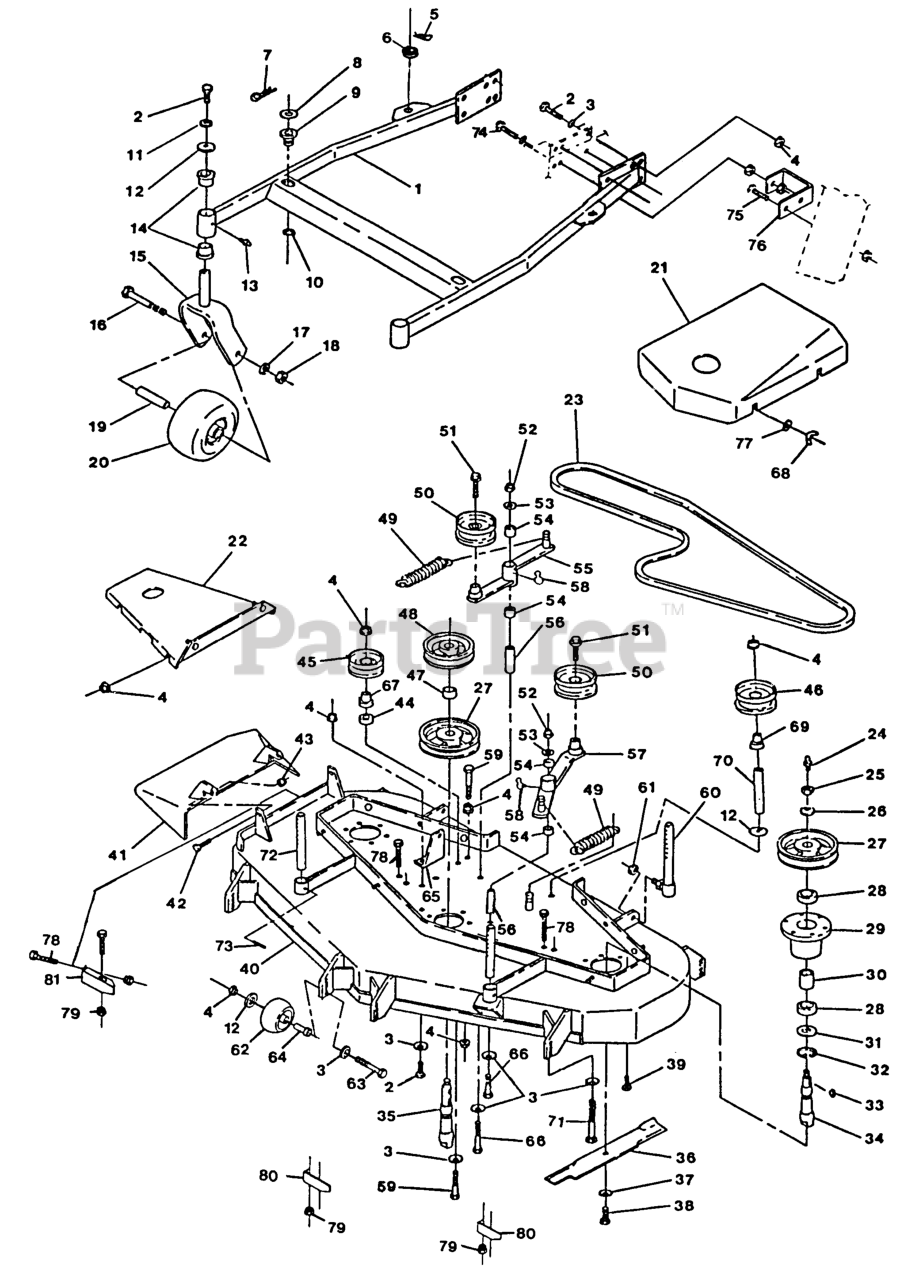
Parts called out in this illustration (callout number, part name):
5	PIN,HAIR COTTER
8	WASHER-FLAT
9	BUSHING-DECK
14	BEARING-FLANGED
23	BELT,BLADE DRIVE
26	WASHER-SPRING
27	SHEAVE,BLADE DRIVE
30	SPACER,BEARING
31	SEAL,MECHANICAL DUST
32	RING,SNAP WLDS N5000-244
34	SPINDLE-OUTER BLADE
35	SPINDLE-CENTER BLADE
37	WASHER-SPRING
39	SCRW,TPTTE HH
41	WLD,CHUTE DISCHARGE
46	PULLEY-IDLER
47	SPACER-TUBE
48	SHEAVE,MOWER DRIVE
49	SPRING-EXTENSION
50	IDLER,PULLEY
54	SLEEVE-BEARING
55	ASM,IDLER ARM
56	BUSHING-PIVOT, IDLER
57	ASM,IDLER ARM
62	ROLLER-SCALP, ANTI
64	BUSHING-ROLLER
65	BRACKET,SPRING ANCHOR
66	SCREW-HH
67	BUSHING-IDLER
68	NUT-WING
69	BUSHING,IDLER
70	SPACER-FENDER
72	ROD,DECK SUPPORT
81	WLD,BAFFLE DISCHARGE
